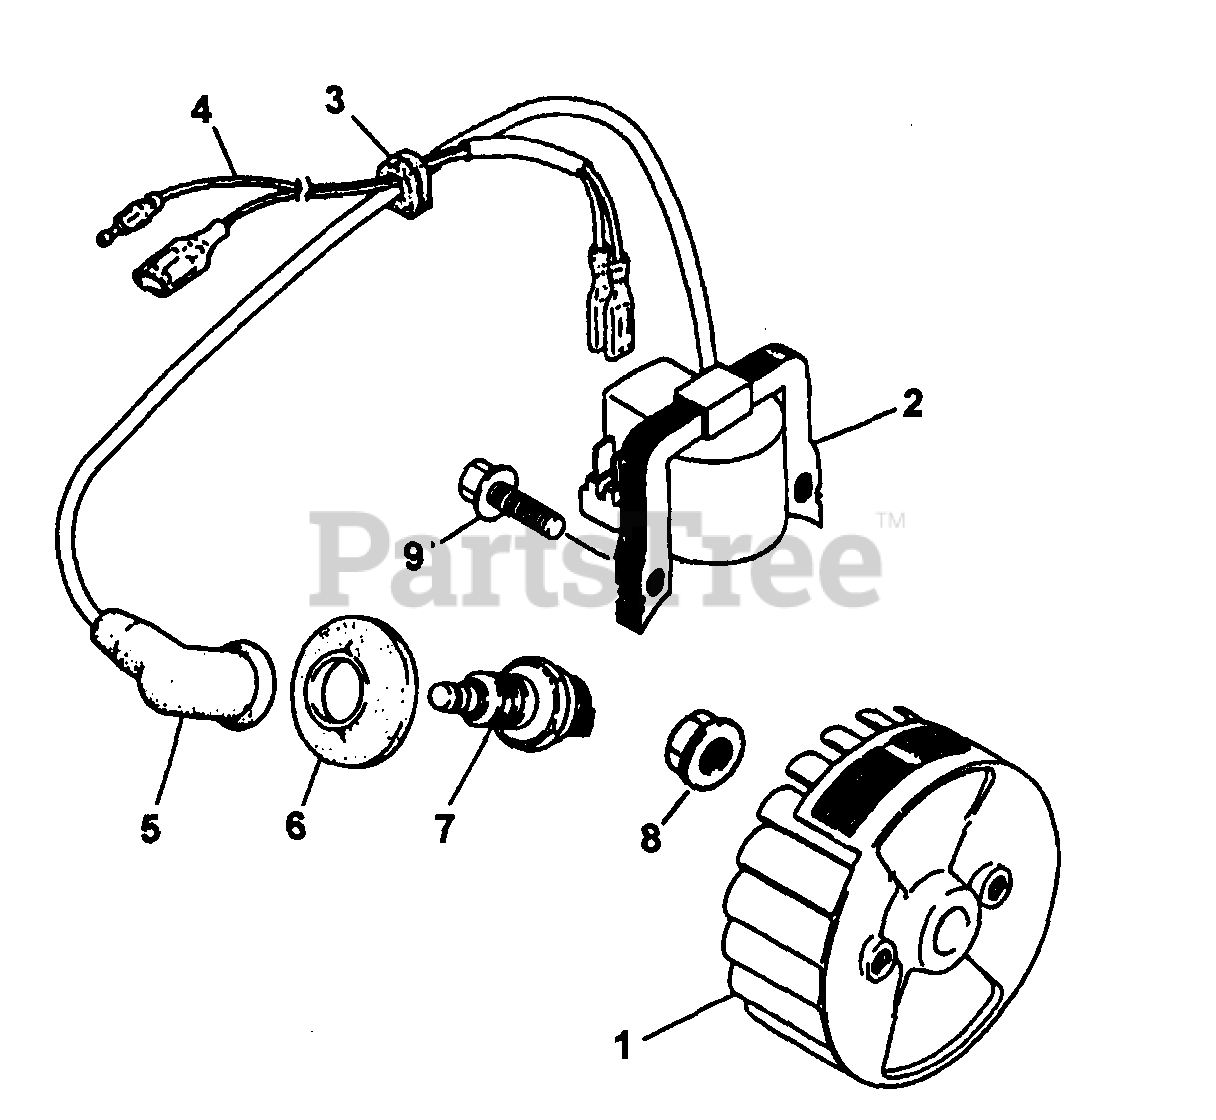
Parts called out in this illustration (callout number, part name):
2	MODULE, IGNITION
3	GROMMET
4	WIRE, LEAD
5	CAP, PLUG
6	CAP, PLUG
7	SPARK PLUG
8	NUT, CONICAL
9	BOLT & WASHER
